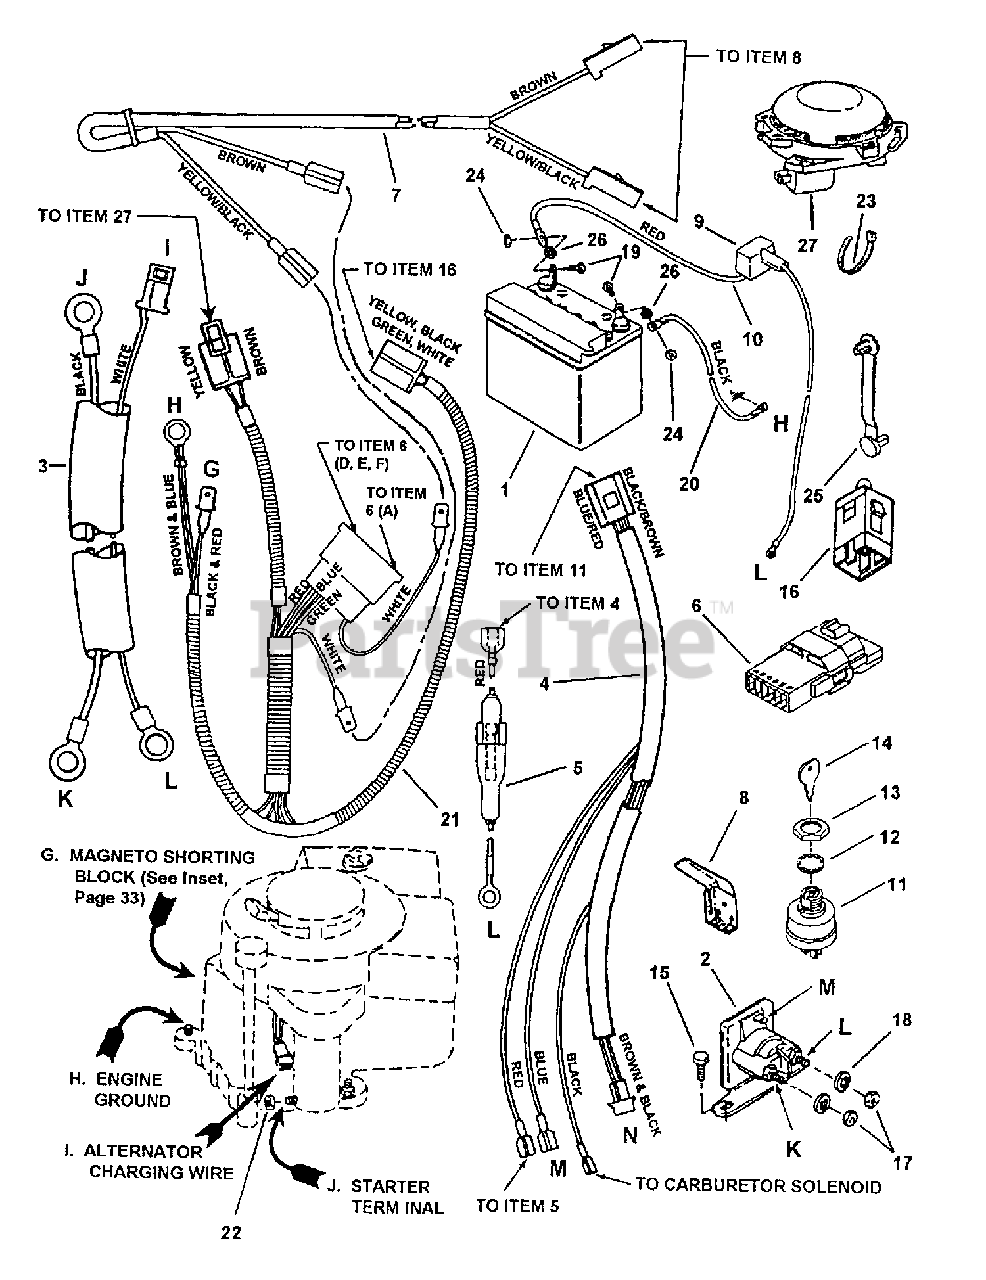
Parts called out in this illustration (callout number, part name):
1	KIT, Battery, 12V, U-1-7RS, 220CCA Dry Charge Snapper No Spill
2	SOLENOID
3	HARNESS, Starter Wiring
4	HARNESS, Ignition Wiring
5	HOLDER, Fuse
6	INTERLOCK Module
7	HARNESS, (Deck Interlock Wiring)
8	SWITCH, Deck Interlock (NO)
9	COVER, Battery Cable
10	CABLE, Positive (Red)
11	SWITCH, Ignition-Afterfire Solenoid
12	WASHER, 5/8" Internal Tooth Lock
13	NUT, 5/8-32 Hex
14	KEY, Switch
15	SCREW, 1/4-20 x 1/2" Hex Washer Self-Tap
16	SWITCH, Operator Presence Control (OPC) Traction (NC/NO)
17	NUT, 1/4-20 Hex, Grade 5 or B
18	WASHER, 1/4" Internal Tooth Lock
19	SCREW, 1/4-20 x 5/8" Hex Head Cap, Grade 5
20	CABLE, Negative (15")
21	HARNESS, Operator Presence Control Wire
22	NUT, 1/4-20 Hex, Grade 5 or B
23	TIE, 7" Long Cable
24	NUT, 1/4-20 Hex Center Lock, Grade 5 or B
25	TIE, 2" Long Cable
26	RETAINER, 1/4" Bolt
27	SWITCH, Seat (NC)
